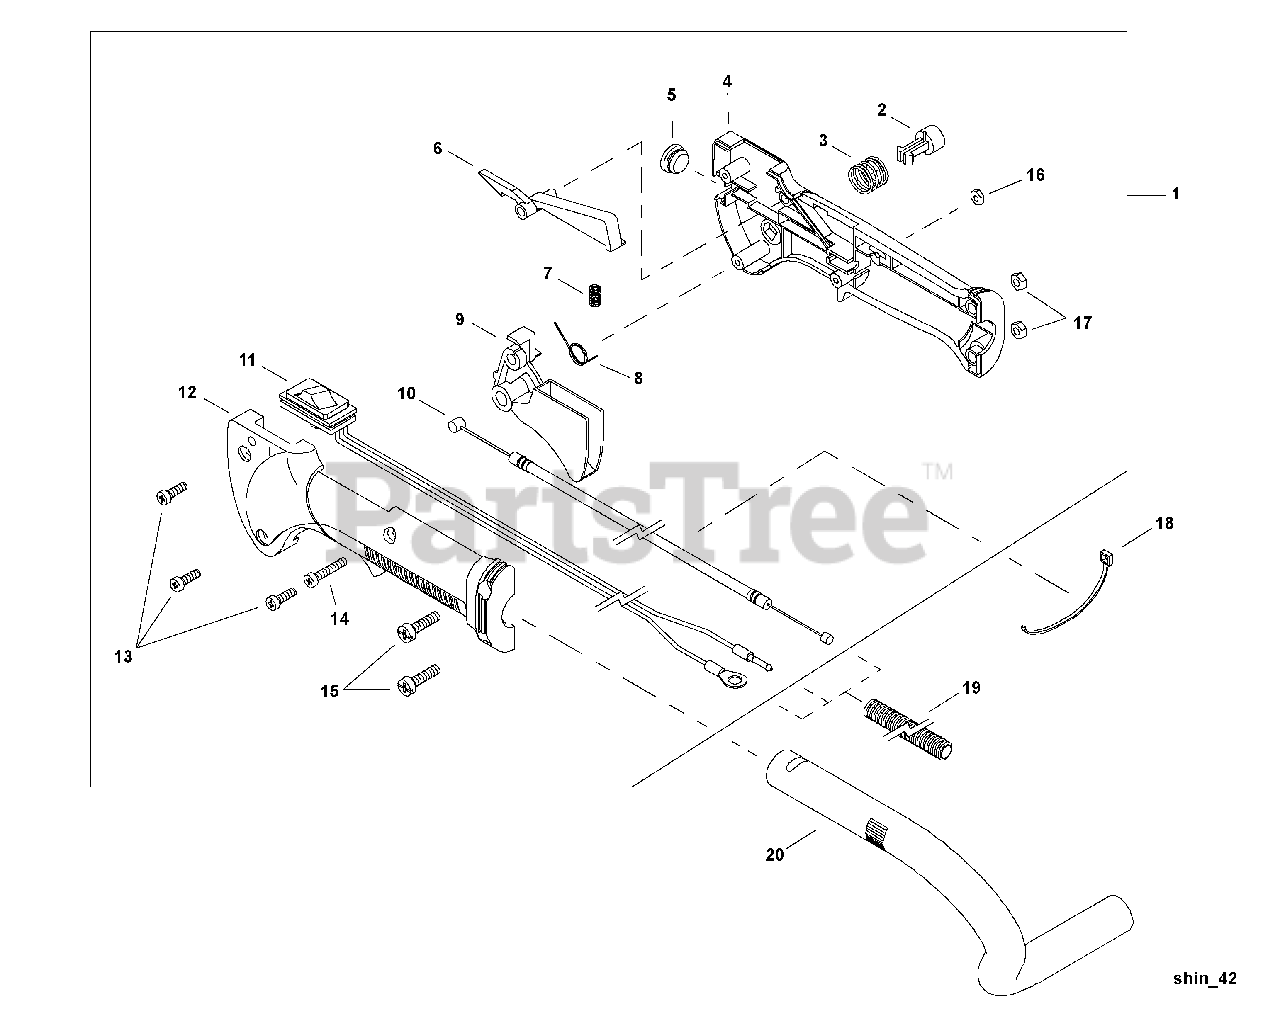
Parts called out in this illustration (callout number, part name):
1	THROTTLE CONTROL ASSY
2	BUTTON, THROTTLE LOCK
3	SPRING, COMPRESSION
4	CONTROL HANDLE - RIGHT
5	PLUG, RUBBER
6	LOCKOUT, THROTTLE
7	SPRING, COMPRESSION
8	SPRING, TORSION
9	TRIGGER, THROTTLE
10	CABLE, THROTTLE
11	SWITCH ASSY, ON-OFF
12	CONTROL HANDLE - LEFT
13	SCREW, TAPPING 4×16
14	SCREW M4×23
15	SCREW M5×20
18	STRAP, TIE
19	TUBE, FLEXIBLE L= 150
20	HANDLE, REAR
